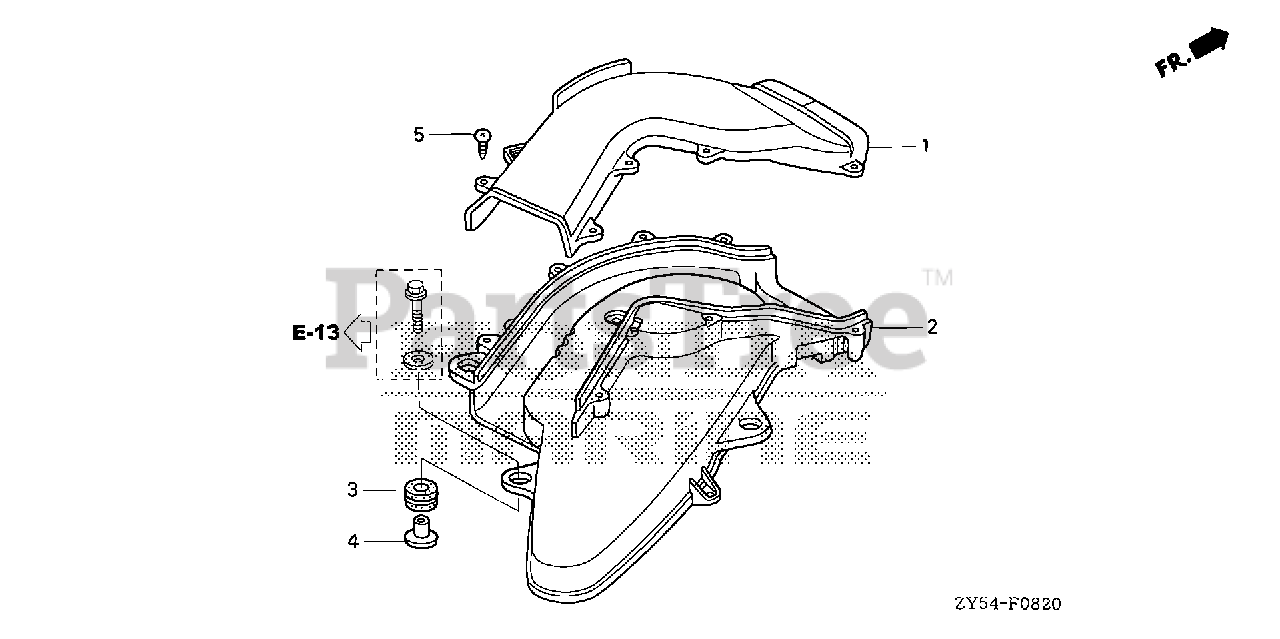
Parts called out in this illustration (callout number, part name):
1	DUCT A, MUFFLER
2	DUCT B, MUFFLER
3	GROMMET, CASE (LOWER)
4	COLLAR, MODULE IGNITION CONTROL CASE (CDI)
5	SCREW, TAPPING (5X20)
